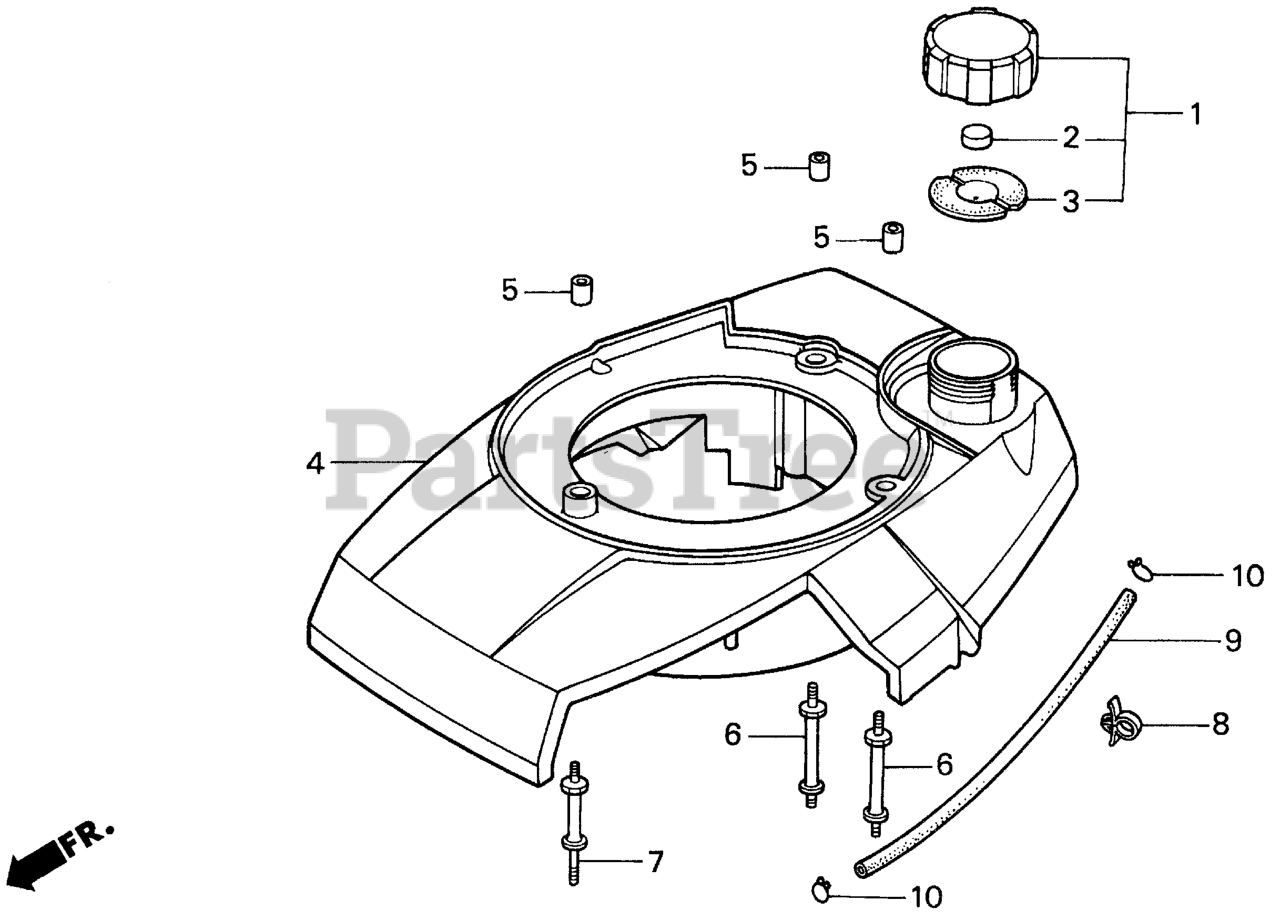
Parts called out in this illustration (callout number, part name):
1	CAP ASSY., FUEL TANK
2	SPONGE, FUEL CAP BREATHER
3	GASKET, FUEL CAP
4	COVER, FAN *R8* (BRIGHT RED)
5	COLLAR, RECOIL STARTER
6	BOLT, SPECIAL STUD
7	BOLT, SPECIAL STUD
8	CLIP, FUEL TUBE
8	CLIP B, CABLE
9	BULK HOSE, FUEL (4.5X3000) (Honda Code 5137104). (4.5X140)
10	CLIP, TUBE (B8)
